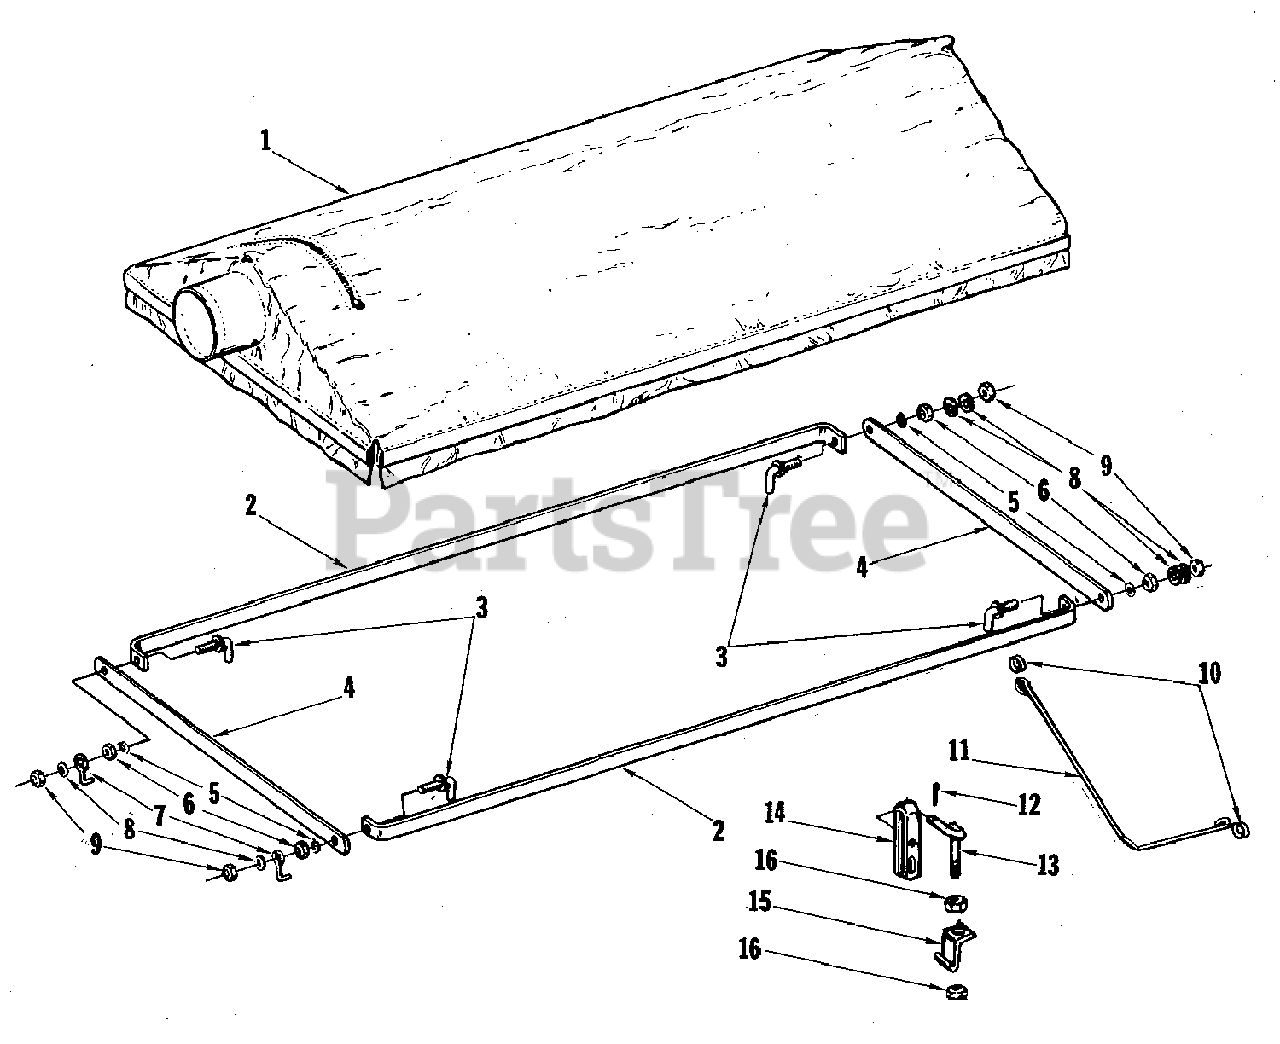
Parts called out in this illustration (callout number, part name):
2	SIDE MEMBER, Frame
3	STUD ASSEMBLY, Special
4	END BRACKET, Frame
5	WASHER, Lock, 5/16"
6	NUT, Hex, 5/16-18
8	WASHER, Flat, 5/16
9	NUT, Hex Lock, 5/16-18
10	LINK, Repair
12	PIN, Cotter, 1/8 x 1
16	NUT, Hex Lock, 3/8-16
